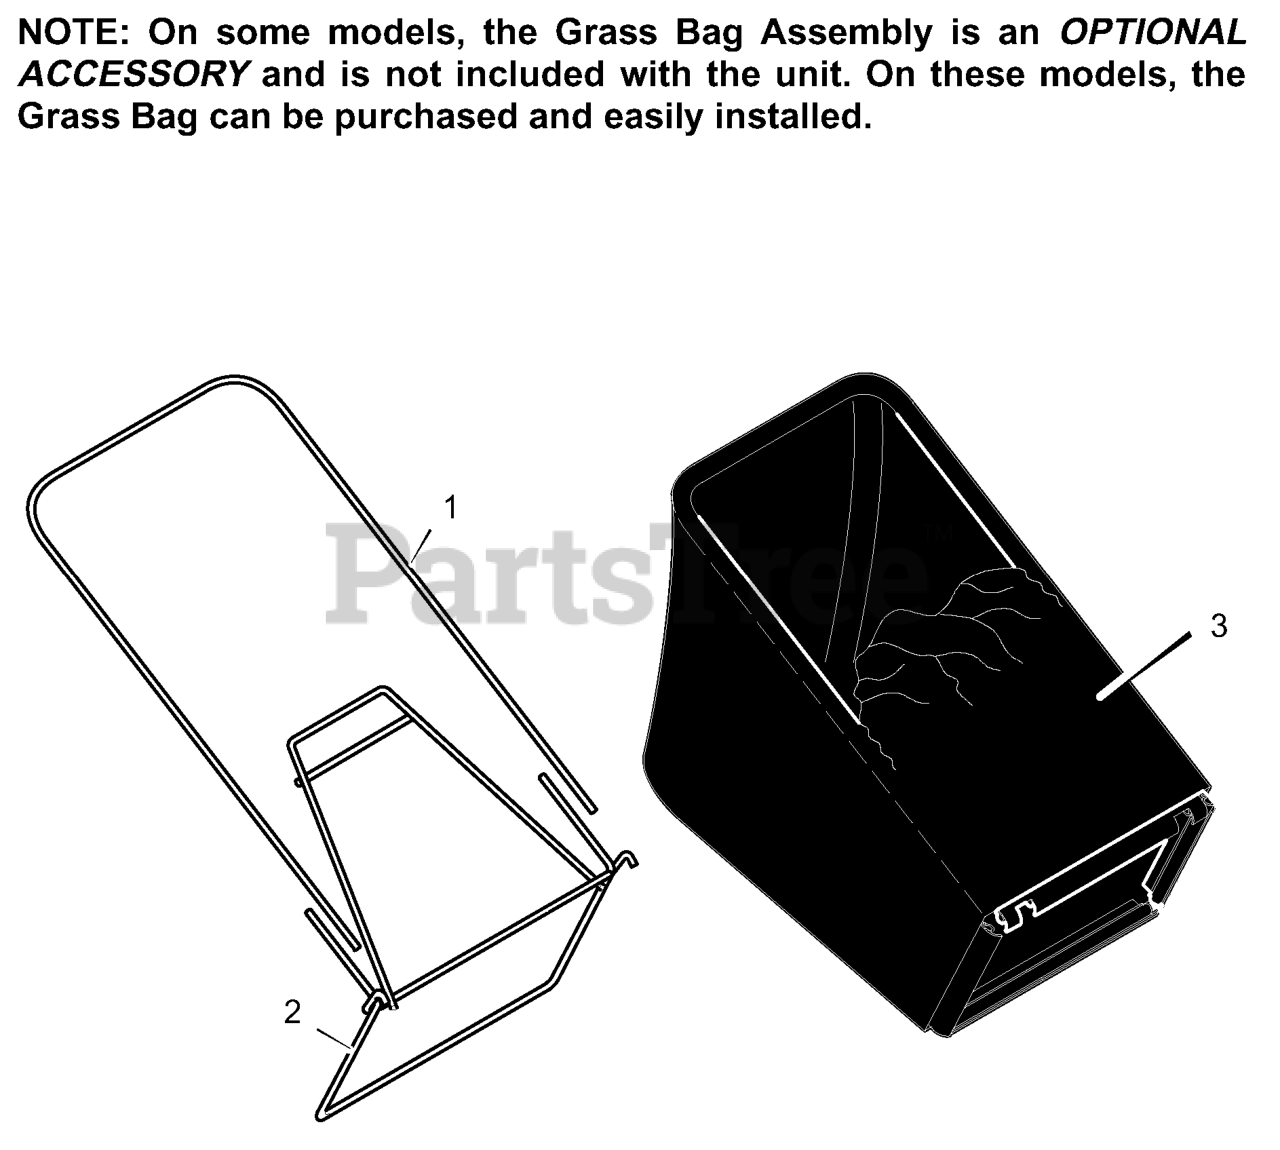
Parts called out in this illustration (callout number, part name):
1	Frame, Top
2	Frame Assembly
3	Bag, Cloth - Black
